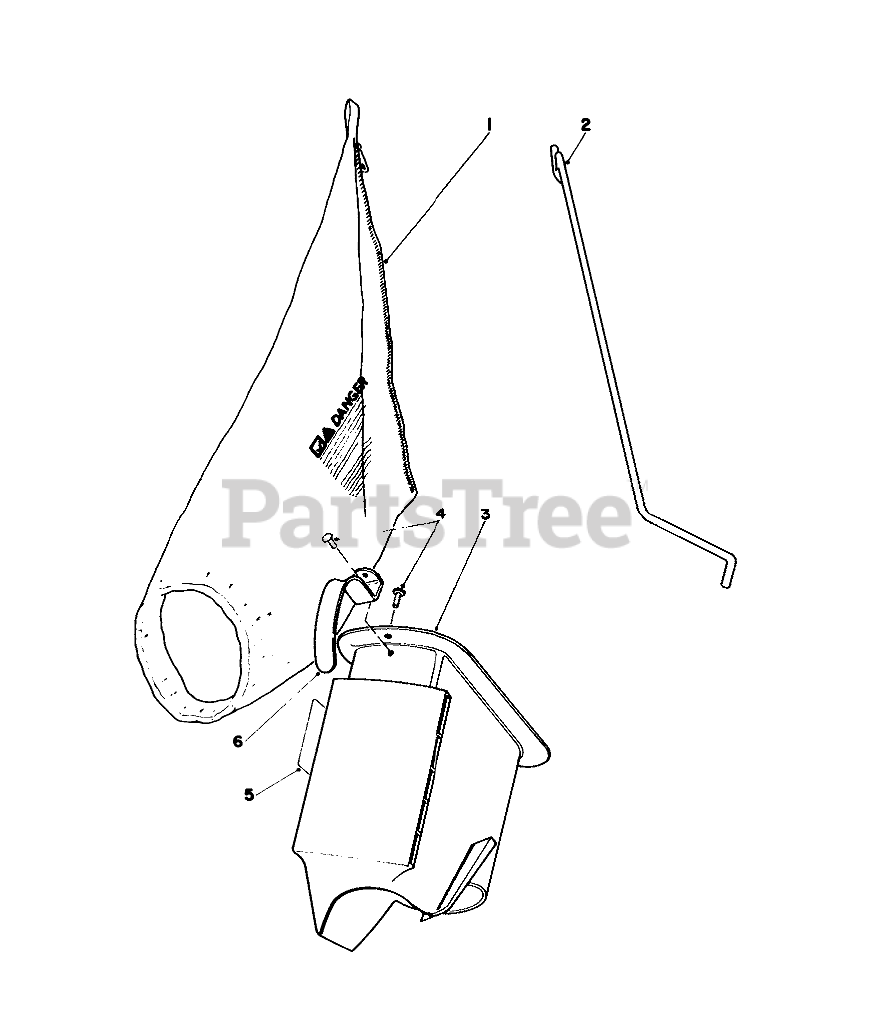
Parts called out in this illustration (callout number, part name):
1	BAG REPLACMNT44-0540
2	BAG ROD
3	Grass Chute (Incl. Ref. #4&6)
4	RIVET 3/16 X 7/16
5	BAG CHUTE DECAL
6	HANDLE-GRASS CHUTE
